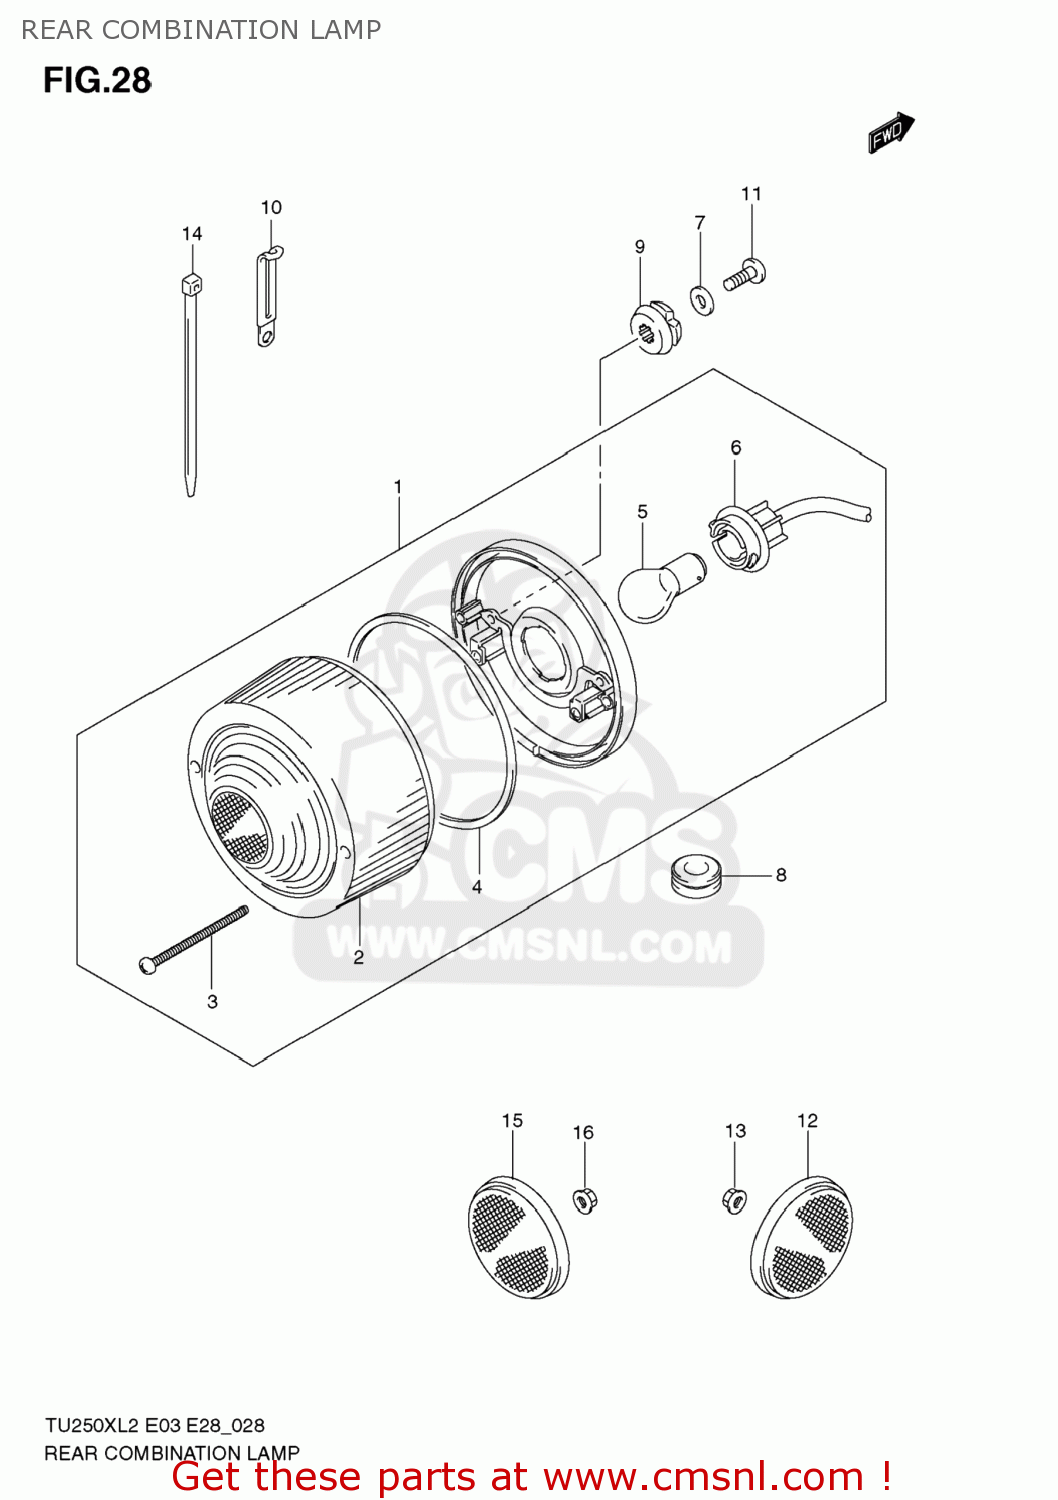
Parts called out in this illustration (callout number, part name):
1	LAMP ASSY,RR COMBINATION
2	LENS
3	SCREW
4	GASKET (NAS)
5	BULB(12V21/5W,BF141-49642A)
6	CORD ASSY
7	WASHER(5.5X20X1.2)
8	GROMMET
9	CUSHION
10	CLAMP(L:45 T:0.6)
11	SCREW
12	REFLECTOR ASSY,RR SIDE
13	NUT
14	CLAMP(L:145)
15	REFLECTOR ASSY,RR SIDE
16	NUT
